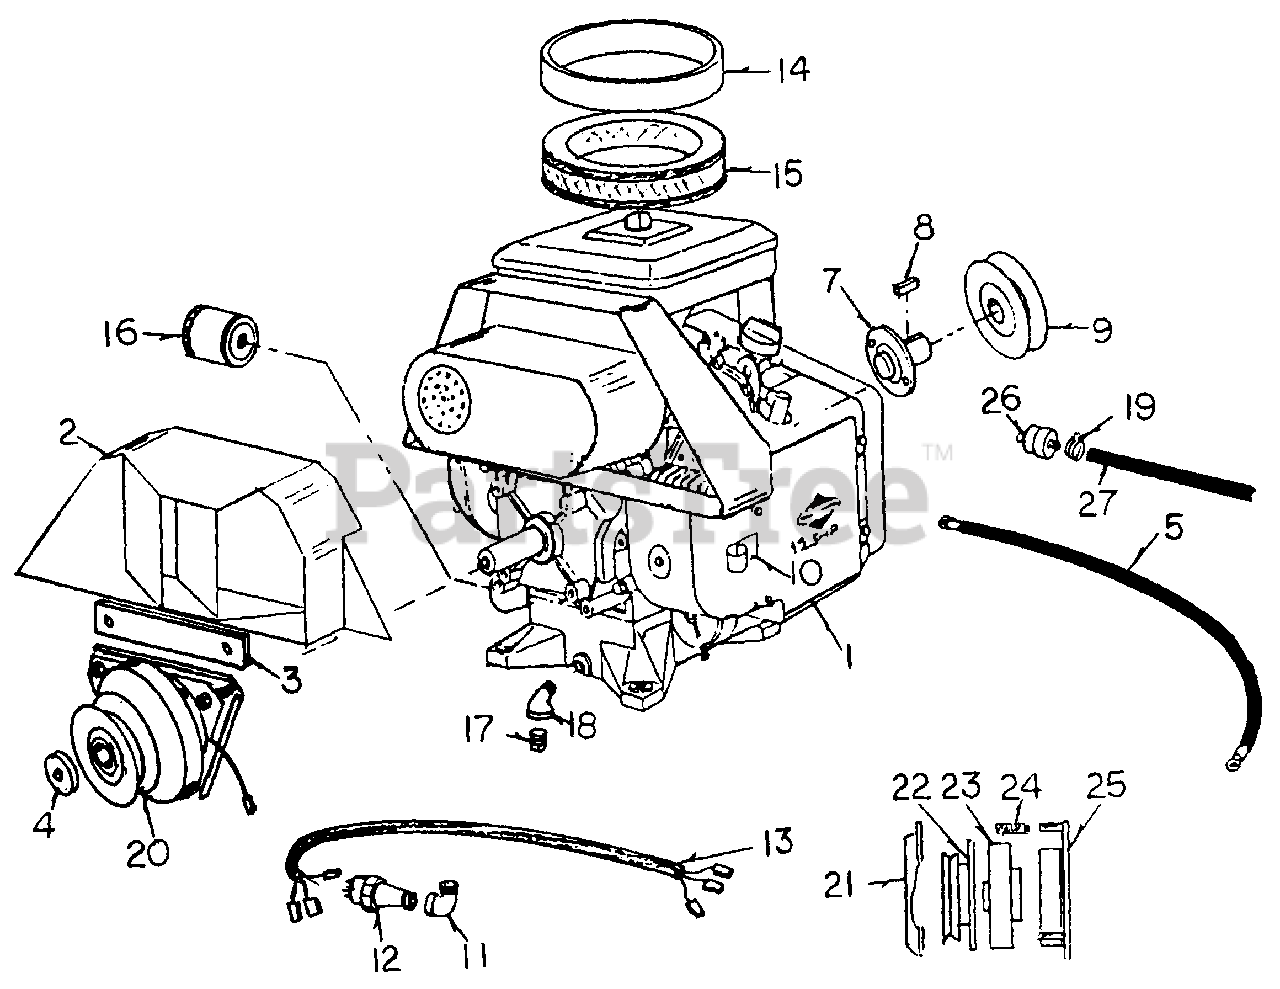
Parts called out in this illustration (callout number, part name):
1	Briggs & Stratton Twin, 12.5 HP
4	Clutch Retainer Washer
8	Key, 1/4" x 1/4" x 1"
10	Starter Cable Retainer
11	Street Elbow, 1/8" x 90°
12	Oil Sending Unit
13	Wire Harness
14	Precleaner
15	Air Cleaner Cartridge
16	Oil Filter
18	Street Elbow, 3/8"
19	Fuel Line Clamp
20	Clutch (Complete)
22	Clutch Armature
23	Clutch Rotor
24	Spring & Nut Set
25	Clutch Coil
26	Fuel Filter
